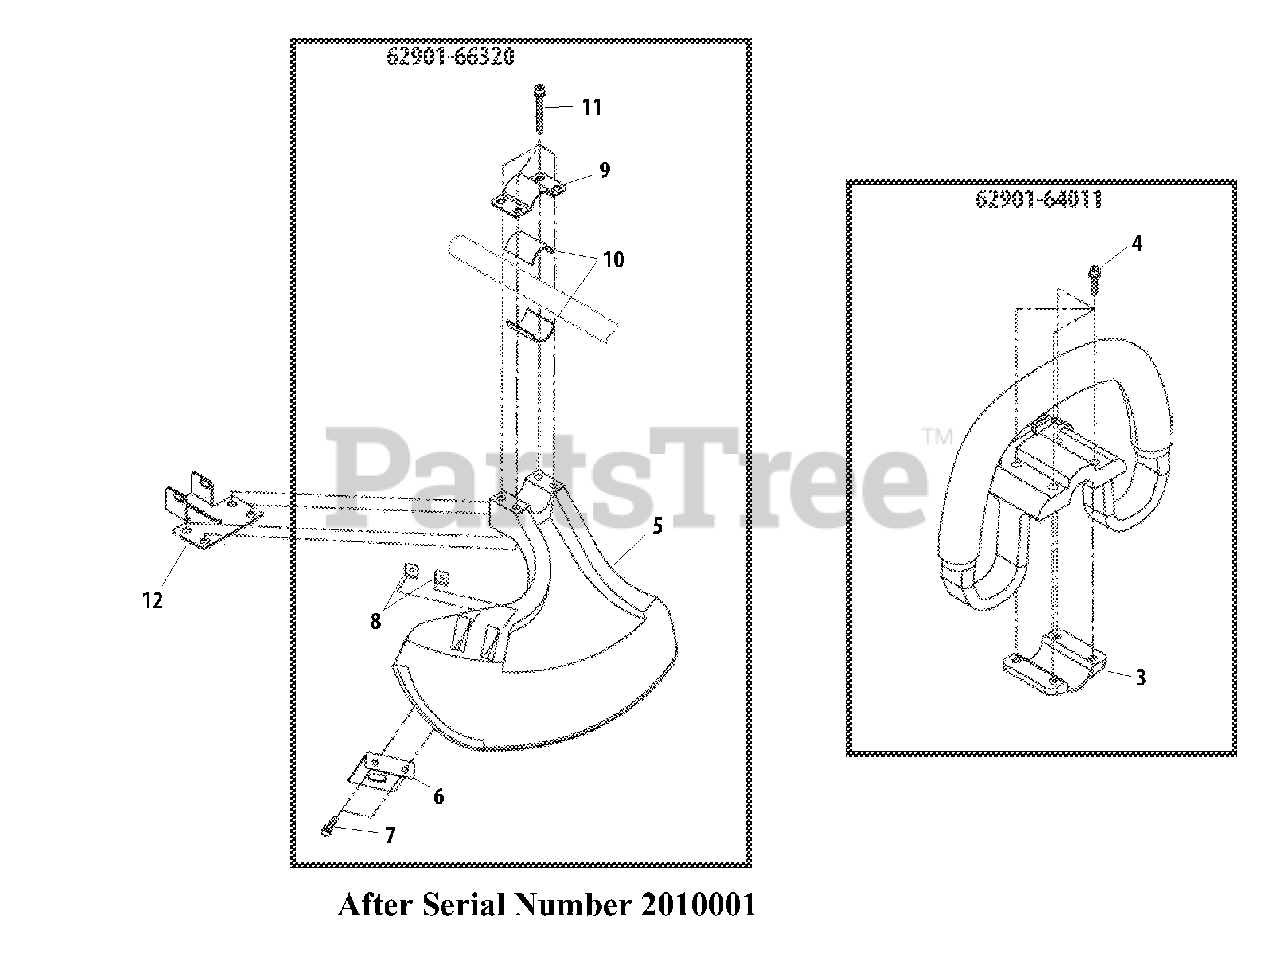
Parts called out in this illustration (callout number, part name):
3	BRACKET, MOUNTING
4	BOLT M5×25
5	SHIELD
6	CUTTER
7	BOLT M5×16
8	NUT M5
9	CLAMP, UPPER
10	SPACER
11	BOLT M5×45
12	PLATE, SHIELD MOUNTING
62901-64011	HANDLE ASSY
62901-66320	GUARD ASSY
